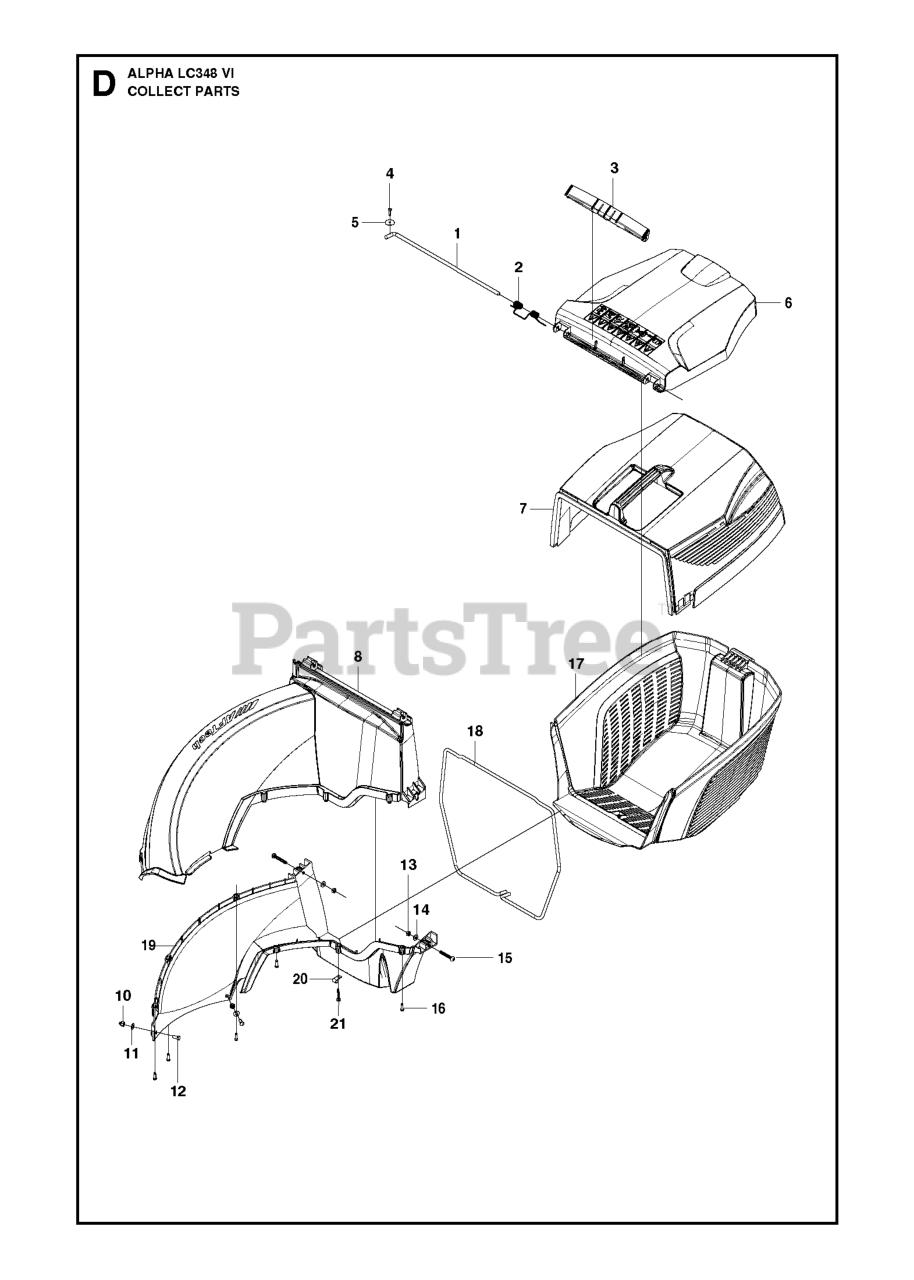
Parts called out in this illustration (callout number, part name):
2	SPRING SAFETY FLAP A009
4	SCREW ITXPANT T50X16 ZN/FE (A
6	HATCH REAR DISCHARGE
7	GRASSBAG UPPER
8	CHUTE UPPER A009
13	NUT FLANGE - M6
16	SCREW ITXPANT T50X16 ZN/FE (A
17	GRASSBAG LOWER
19	CHUTE LOWER A009
